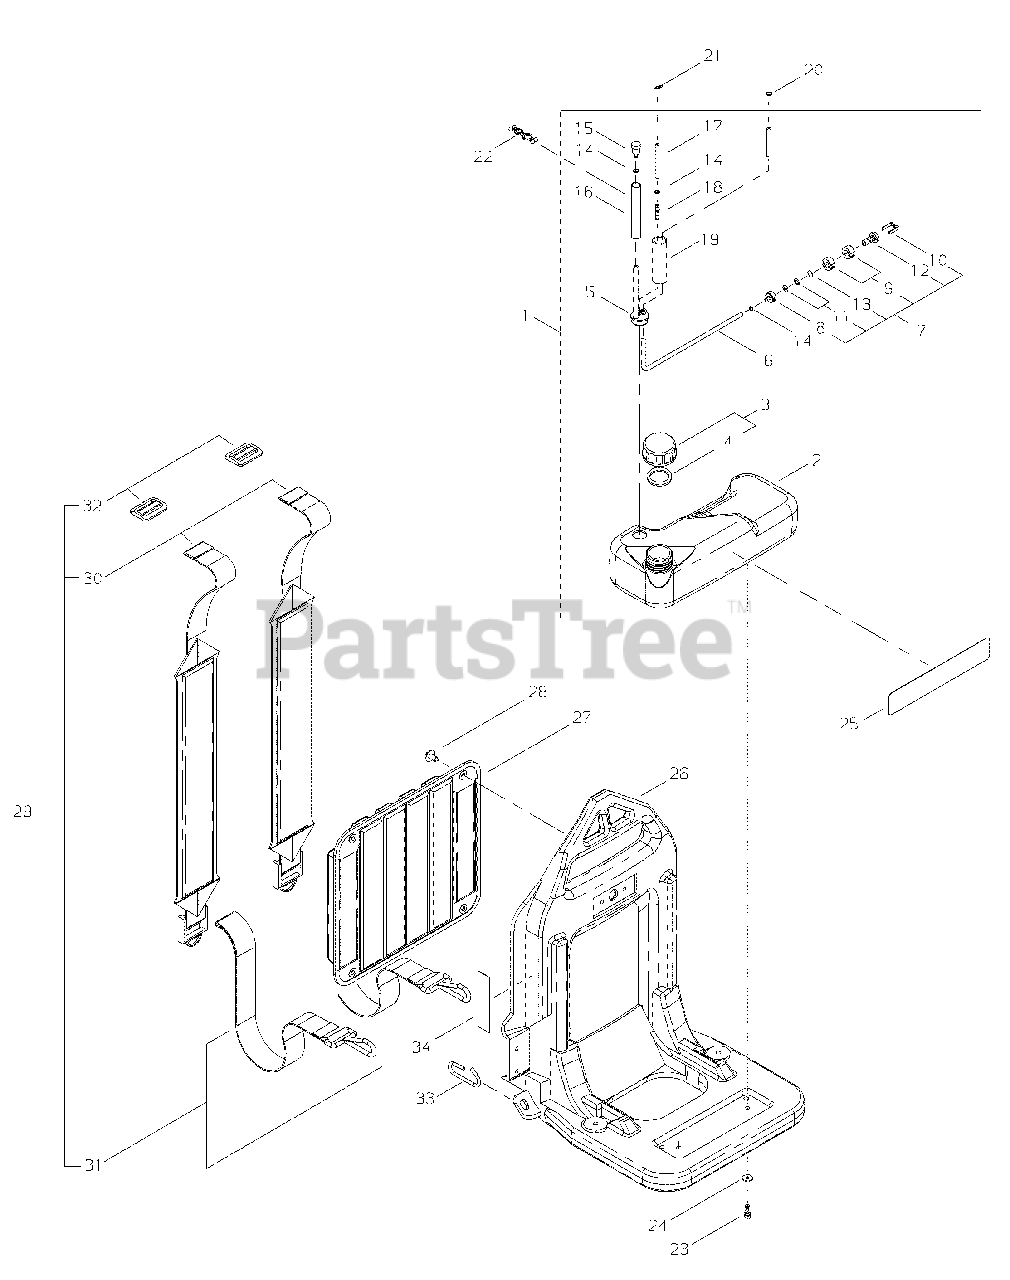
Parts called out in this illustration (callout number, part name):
1	FUEL TANK ASSY
2	TANK, FUEL
3	CAP ASSY
4	GASKET, CAP
5	PIPE ASSY
6	PIPE - FUEL
7	FILTER, FUEL
8	WEIGHT, FUEL FILTER
9	FILTER, FUEL
10	CLIP, FILTER
11	SCREEN, FILTER
12	CASE, FILTER
13	RING, RETAINING
14	RING, RETAINING - 6
15	VENT, FUEL TANK
16	TUBE
17	TUBE - 5X3X110
18	CONNECTOR, PIPE
19	SLEEVE X12 X X11 X L70
20	CLIP - SPRING
21	RING, RETAINING - 6
22	CLIP
23	SCREW - 5X14
24	COLLAR
25	LABEL - TRADE
26	FRAME
27	PAD
28	CLIP
29	HARNESS ASSY
30	STRAP, BACKPACK
31	STRAP
32	BUCKLE
33	HOOK, SPRING
34	LABEL - CAUTION
